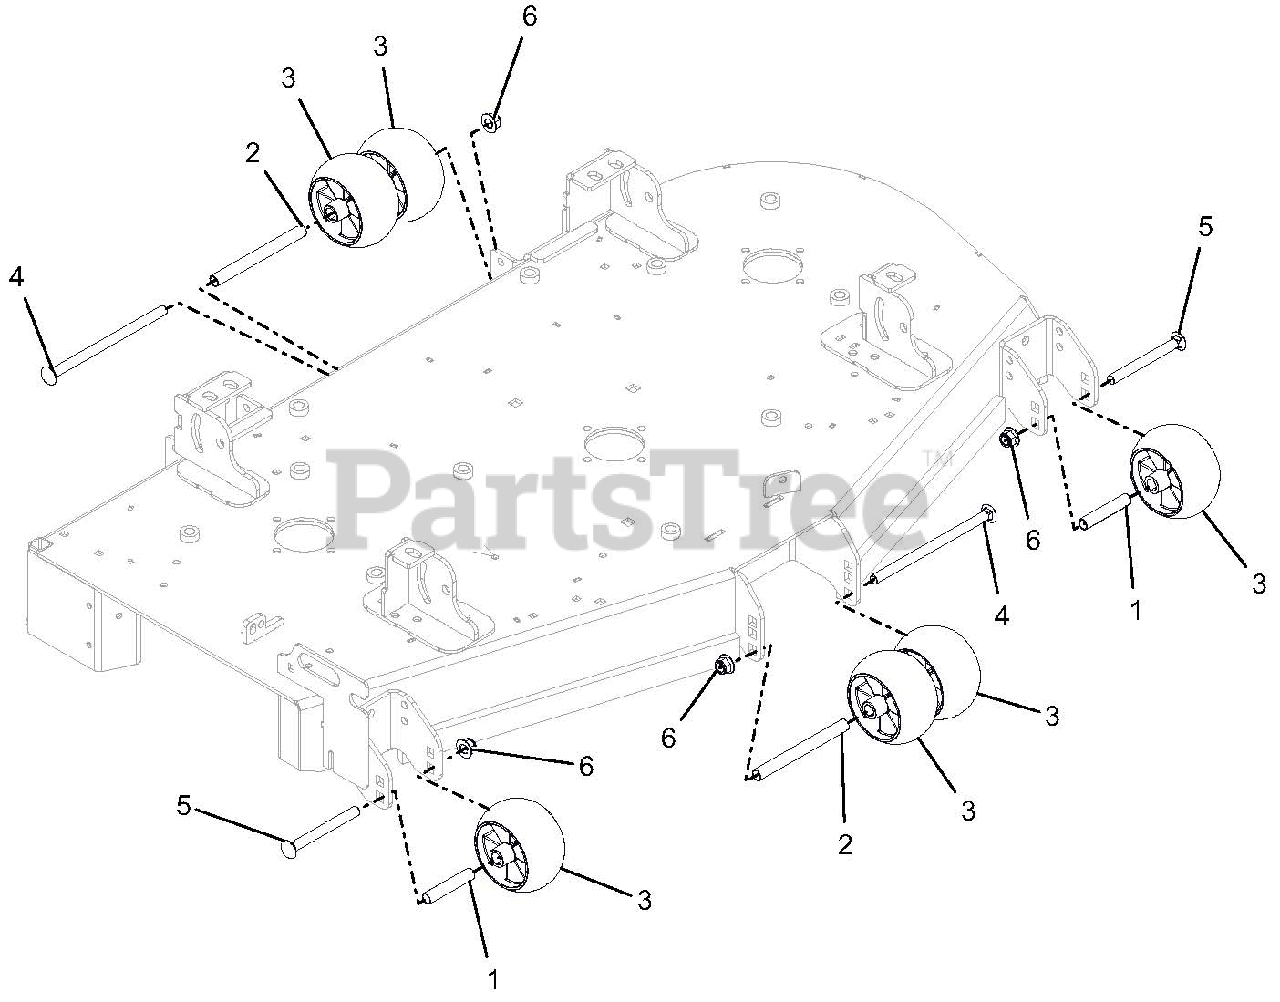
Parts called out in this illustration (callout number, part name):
1	SPACER, .510X.625X3.35
2	SPACER, .510X.625X6.50
3	ANTI-SCALP WHEEL - 5X3 CTR
4	@BLT-RDHDSQNK .50-13X8.50 G5YZ
5	BLT-RDHDSQNK .50-13X5.00 GR5YZ
6	@NUT-LK-NYL-FLG .50-13 YWZC
